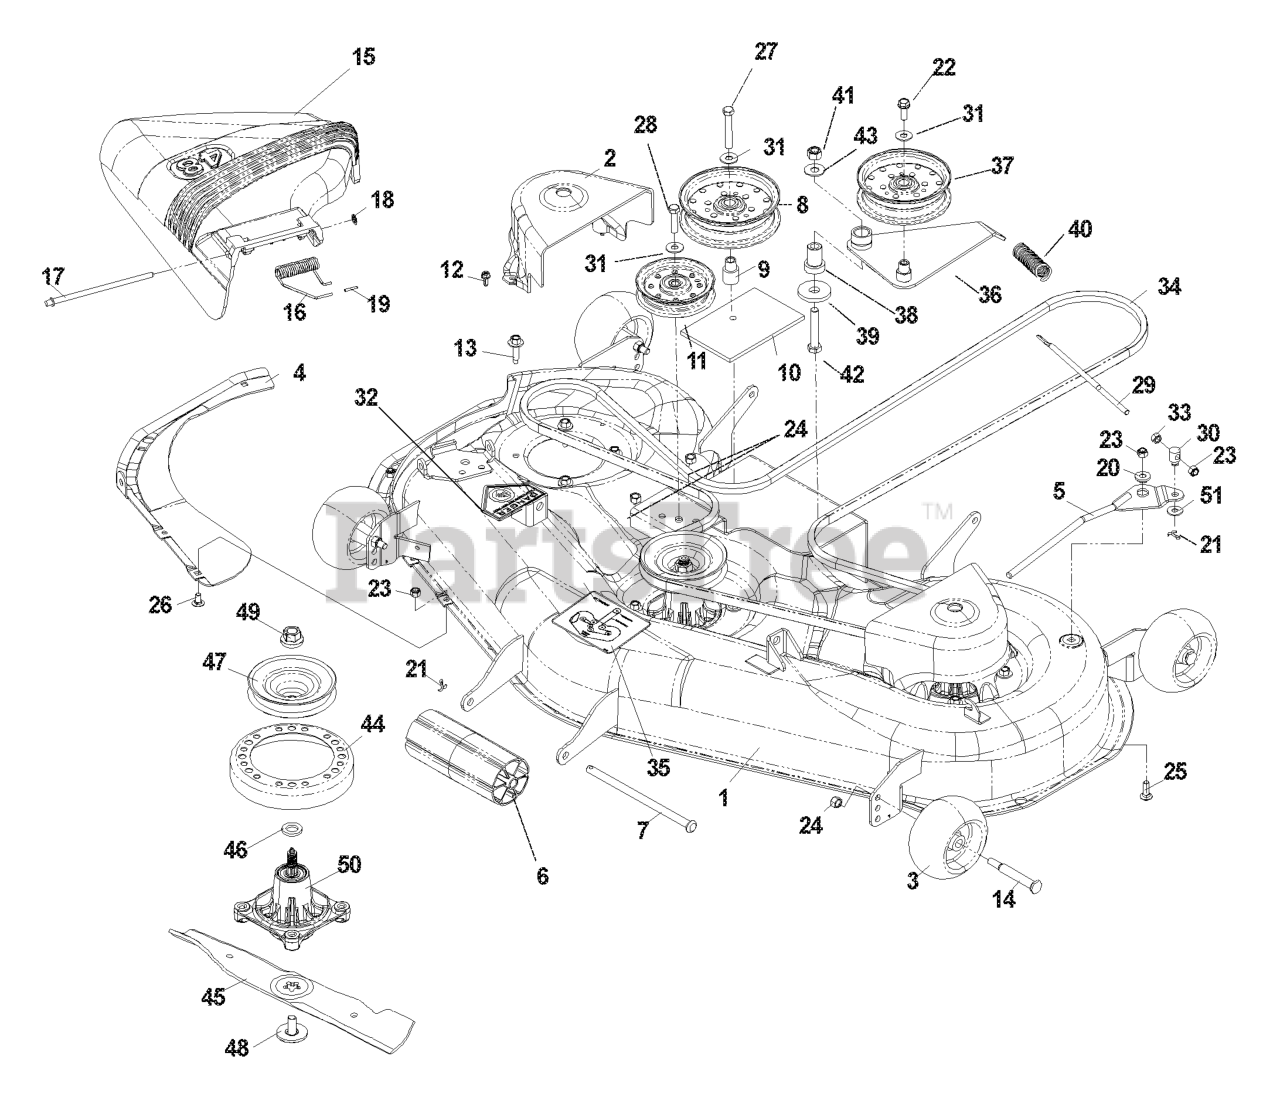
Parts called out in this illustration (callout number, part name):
1	DECK W/DECALS 48" HUS
2	BELT SHIELD
3	GAUGE WHEEL
4	VORTEX MOWER BAFFLE
5	TENSION RELIEF LEVER BLK
6	NOSE ROLLER-48"
7	NOSE ROLLER ROD
8	IDLER PULLEY
9	IDLER BUSHING
10	SUPPORT PLATE, BLACK
11	FLAT IDLER PULLEY
12	SCREW- 1/4-20 X 5/8
13	WASHER HEAD SCREW
14	SHOULDER BOLT 1/2X2-5/8 ZD SPE
15	DISCHARGE CHUTE
16	TORSION SPRING
17	HINGE ROD
18	PUSH NUT
19	CAP-SLEEVE
20	PIVOT BUSHING
21	RP_COTTER PIN 1/8 X 3/4
22	4CS 3/8C X 1 SERRATED HEAD
23	NUT 5/16 NYLOC
24	NUT 3/8-16 NYLOC
25	RHSNB 5/16C X 1
26	CARRIAGE BOLT 5/16C X 5/8"
27	SCREW 3/8C X 2 3/4 HEX CAP
28	HCS 3/8-16 X 1 3/4 GR5
29	TENSION RELIEF LINKAGE
31	WASHER 5/16 FLAT
32	DECAL, CPSC
33	NUT 5/16C HEX
34	BELT, DECK
35	DECAL, BELT ROUTING
36	DECK IDLER ARM WELDMENT
37	IDLER PULLEY
38	IDLER SPINDLE
39	WASHER, SUPPORT
41	NUT 1/2-13 HEX NYLOC ZD
42	SCREW, 1/2C X 3 HEX CAP
43	WASHER 1/2 FLAT
44	STRIPPER-ROUND-UNIVERSAL
45	BLADE-HIGH LIFT/48"
46	WASHER-SPACER
47	DRIVEN PULLEY-48"
48	BLADE BOLT ASSY-7/16" TB REPL
49	LOCKNUT - 9/16
50	CUTTER HOUSING
51	WASHER 3/8 SAE FLAT
